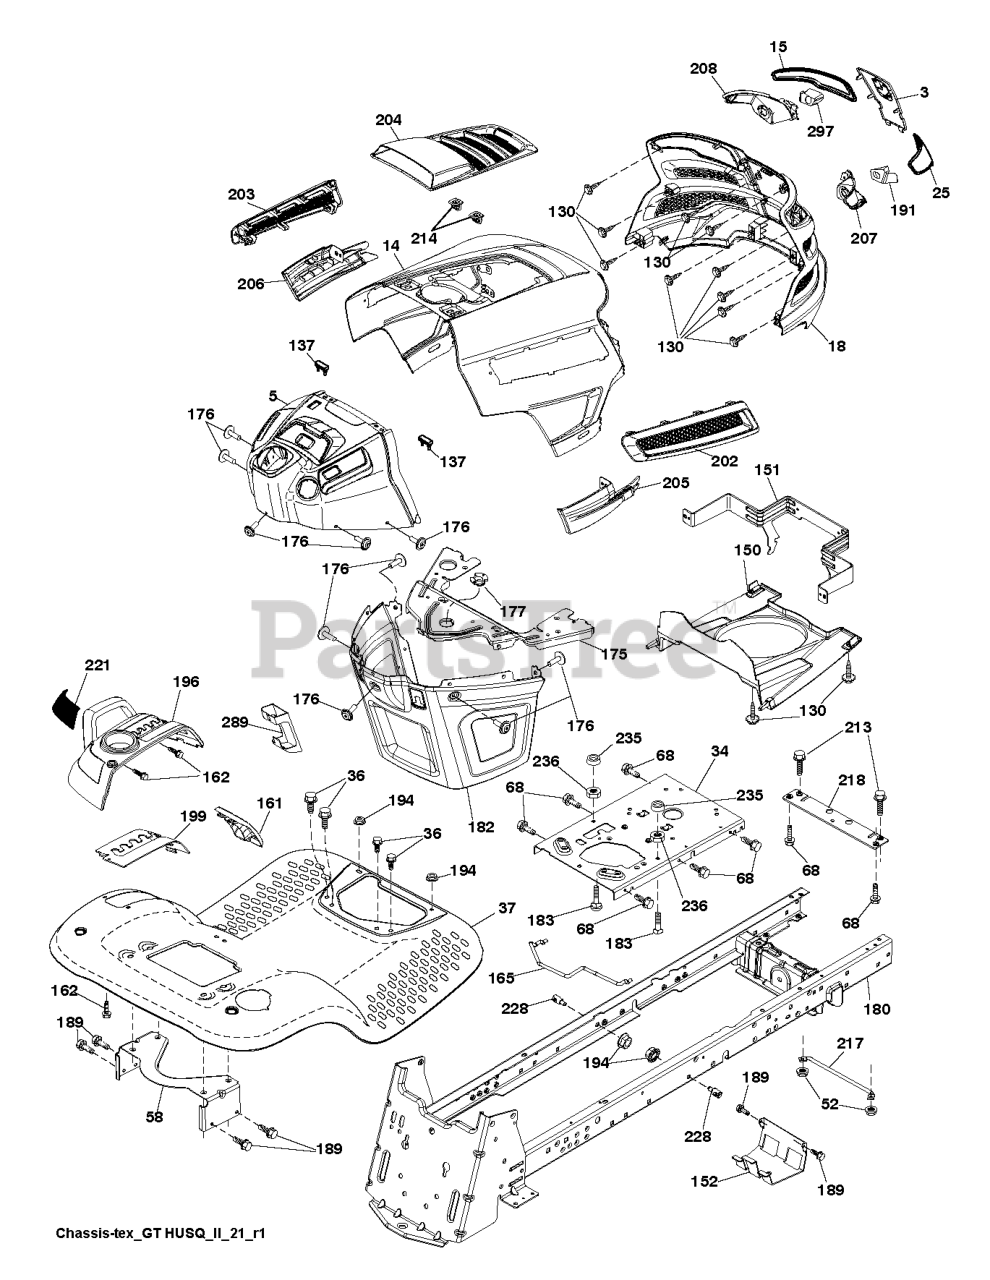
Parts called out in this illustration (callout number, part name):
3	APPLIQUE.SUBASM.GT.HUSQ.II
5	DASH.UPP.GT2.SM.PTO.MCHOKE
14	HOOD.ASM.HUSQVARNA.GT.TEX.ORAN
15	LENS.HEADLIGHT.LH.GTII.2011
18	GRILLE.SUBASM.GT.HUSQ.II
25	LENS.HEADLIGHT.RH.GTII.2011
34	PLATE.ENGINE.WELDED.CHASSIS
36	SCREW 5/16"
37	FENDER.PNT.TX.GT.CH/FW.ORANGE
52	LOCKNUT
58	BRKT.SUPPORT.FNDR/TANK
68	Screw 5/16-18 x 1/2 Hex, Self Tapping 5/16-18 x 1/2
130	SCREW.#10 X 0.750.BOS
137	BUMPER DASH
150	AIR.DUCT.GTV.BLACK
151	BRACKET.PIVOT.HOOD.GT.HUSQ.II
152	SHIELD.BROWNING.W/TEX
161	CONSOLE.FUEL.WINDOW.HU
162	SCREW.HI-LO.CONSOLE
165	SUPPORT.TANK.REAR.W/TEX
175	PLATE.CROSSMEMBER.HUSQ
176	SCREW.#10-24X5/8.RN.QU
177	BUSHING, STEERING
180	CHASSIS.GT.SLOPED.DRAWBAR.
182	DASH.LOWER.COMMON.12V.ADAPTOR
183	BOLT.5/16-18X1-1/4 FULL THD
189	SCREW
191	INSERT.REFLECTIVE.RH.HUSQ.GTII
194	NUT LOCK HEX FLANGE 5/16-18
196	RP CONSOLE.ASM.DECKLFT.W/
199	PLATE.DECK.LIFT.HUSQVARNA.GT
202	VENT.SIDE.RH.GT.HUSQ.II.
203	VENT.SIDE.LH.GT.HUSQ.II.498
204	VENT.TOP.HUSQ.GT2
205	SIDE.TRIM.RH.GT.HUSQ.II
206	SIDE.TRIM.LH.GT.HUSQ.II.GRAY
207	BEZEL LIGHT.RH.GT.II.MYLAR
208	BEZEL LIGHT.LH.GT.II.MYLAR
213	BOLT
214	CLIP.RETAINER.TINNER.
217	ROD.PIVOT.HOOD
218	X-PIECE.HOOD.STOP.NON/
221	REFLECTOR.LH.TEX GT HU
228	STUD.FASTNER.W/ANTI-ROTATE
235	SPACER FENDER
236	NUT.CENTERLOCK.5/16-
289	PLUG.N/CRUISE.COMMON.YT/GT.BLK
297	INSERT.REFLECTIVE.LH.HUSQ.GTII
